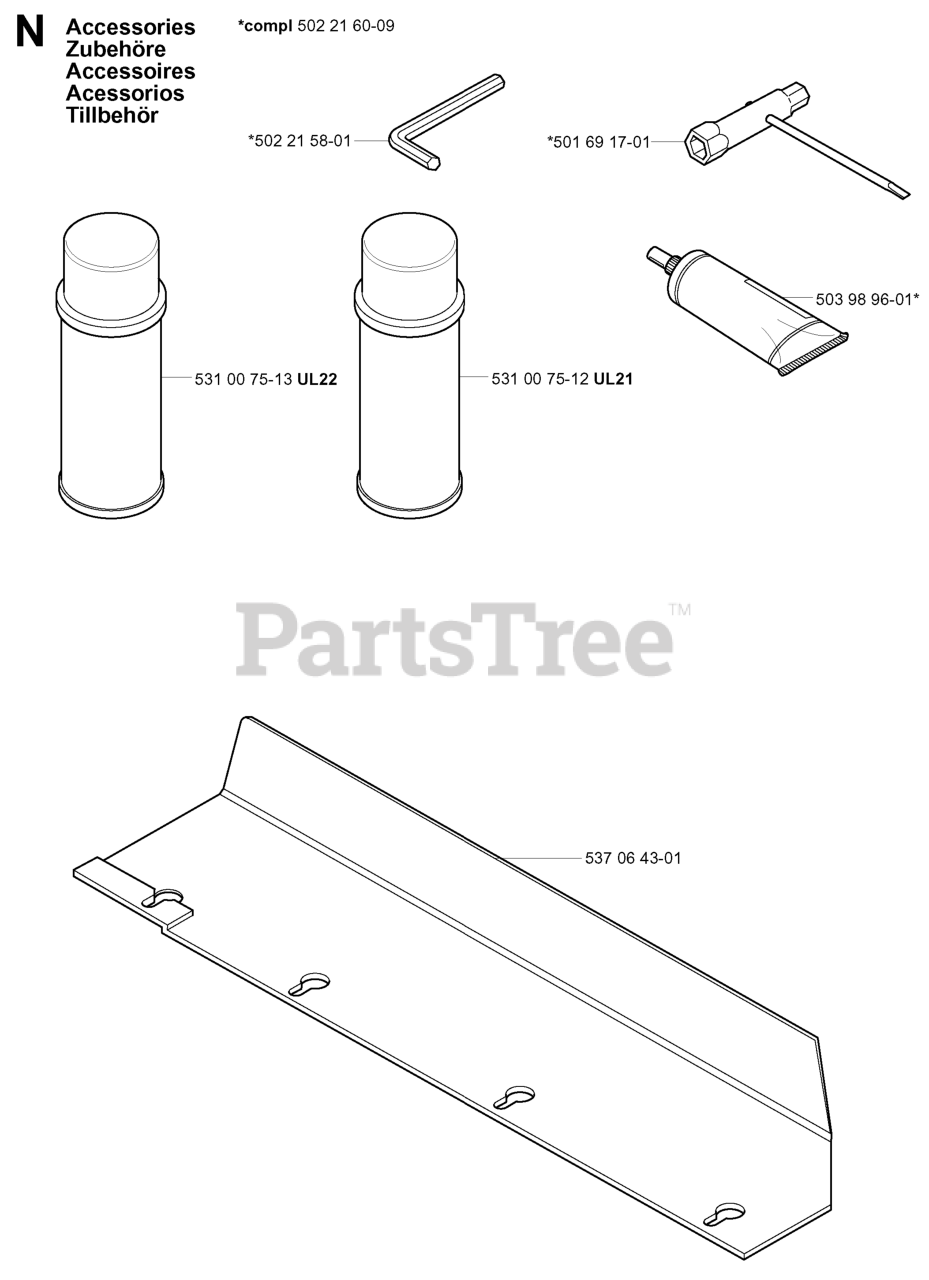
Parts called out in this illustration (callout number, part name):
1	LOCKNUT, M6-1.00 NYLON INSERT
2	BOLT - M6X1.0X40 HEX FLNG HD
3	SCREW, M6 X 16 TT HX FL HD
4	ASSY, ROTOR, BRAKE, FRONT, WT
5	ROTOR,BRAKE,FRONT,WT
6	STUD, WHEEL LUG
7	ASSEMBLY, BRAKE LINE, REAR
8	BRACKET, TEE, BRAKELINE
9	CLIP, BRAKE LINE
10	BRKT, LINE, HYD, RECVR
11	BRAKELINE, FRONT, ASS'Y
12	TIE WRAP , 11" NYLON
